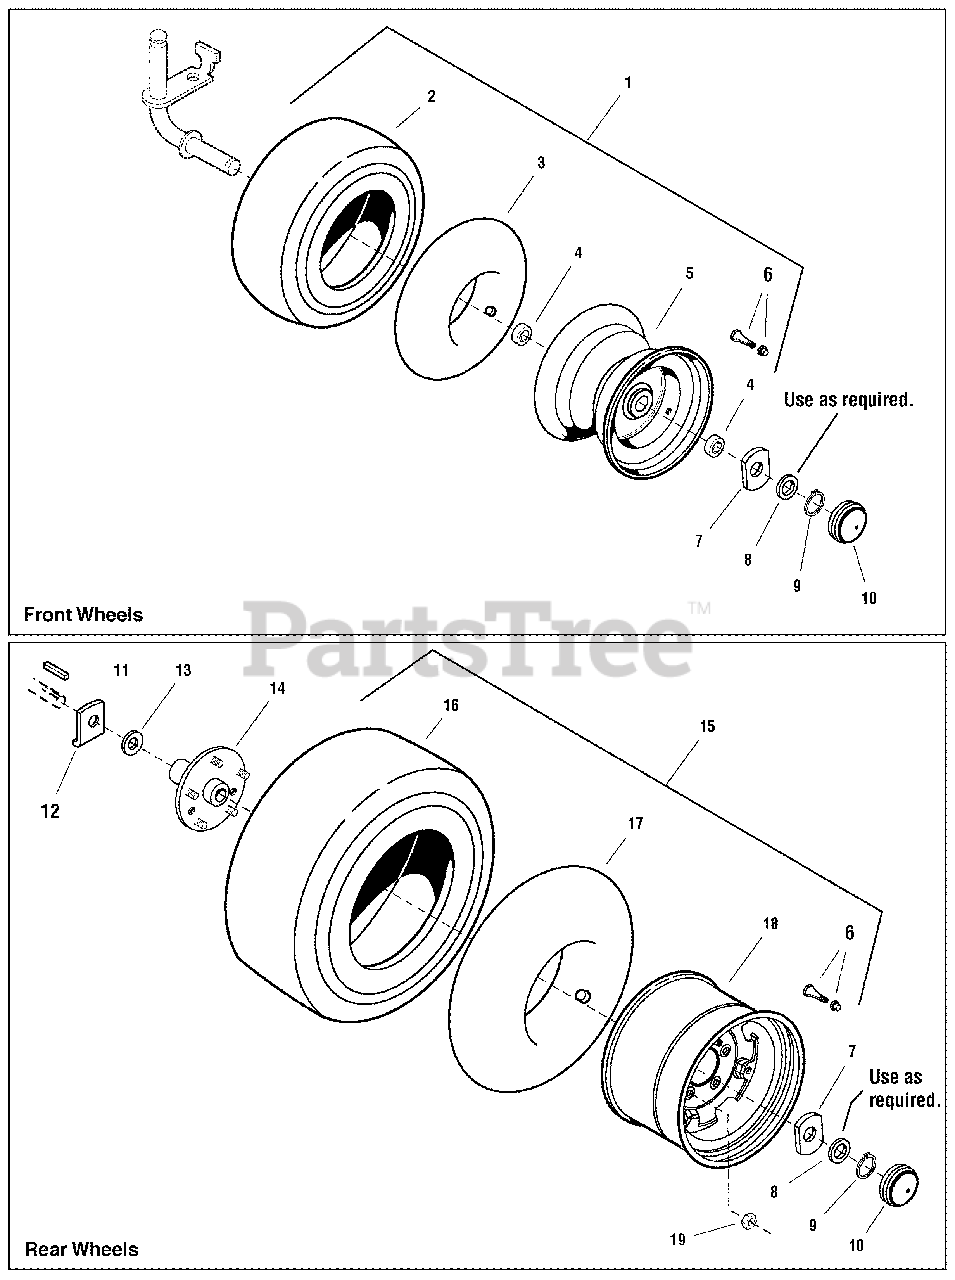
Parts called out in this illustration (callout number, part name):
1	WHEEL & TIRE ASSEMBLY (Includes Ref. Nos. 2, 3, 4, 5 & 6)
2	TIRE, 16 x 6-1/2
4	BEARING, Ball 25M
5	WHEEL, w/Bearings
6	VALVE STEM & CAP
7	WASHER, Special
8	WASHER, 1.00
9	RING, Retainer
11	KEY, Hi-Pro, 1/4 x 2
12	WASHER, Axle Seal
13	WASHER, 1.00
14	PLATE & HUB WELDMENT
15	WHEEL & TIRE ASSEMBLY (Includes Re. Nos. 6, 16, 17, 18 & 19)
16	TIRE, 24 x 12 - 12 Super Turf
17	TUBE, Tire 23 x 10-1/2 - 12
18	WHEEL, 8-1/2 Wide 12 Diameter
19	NUT, Hex 7/16-20 For Wheel Bolt
